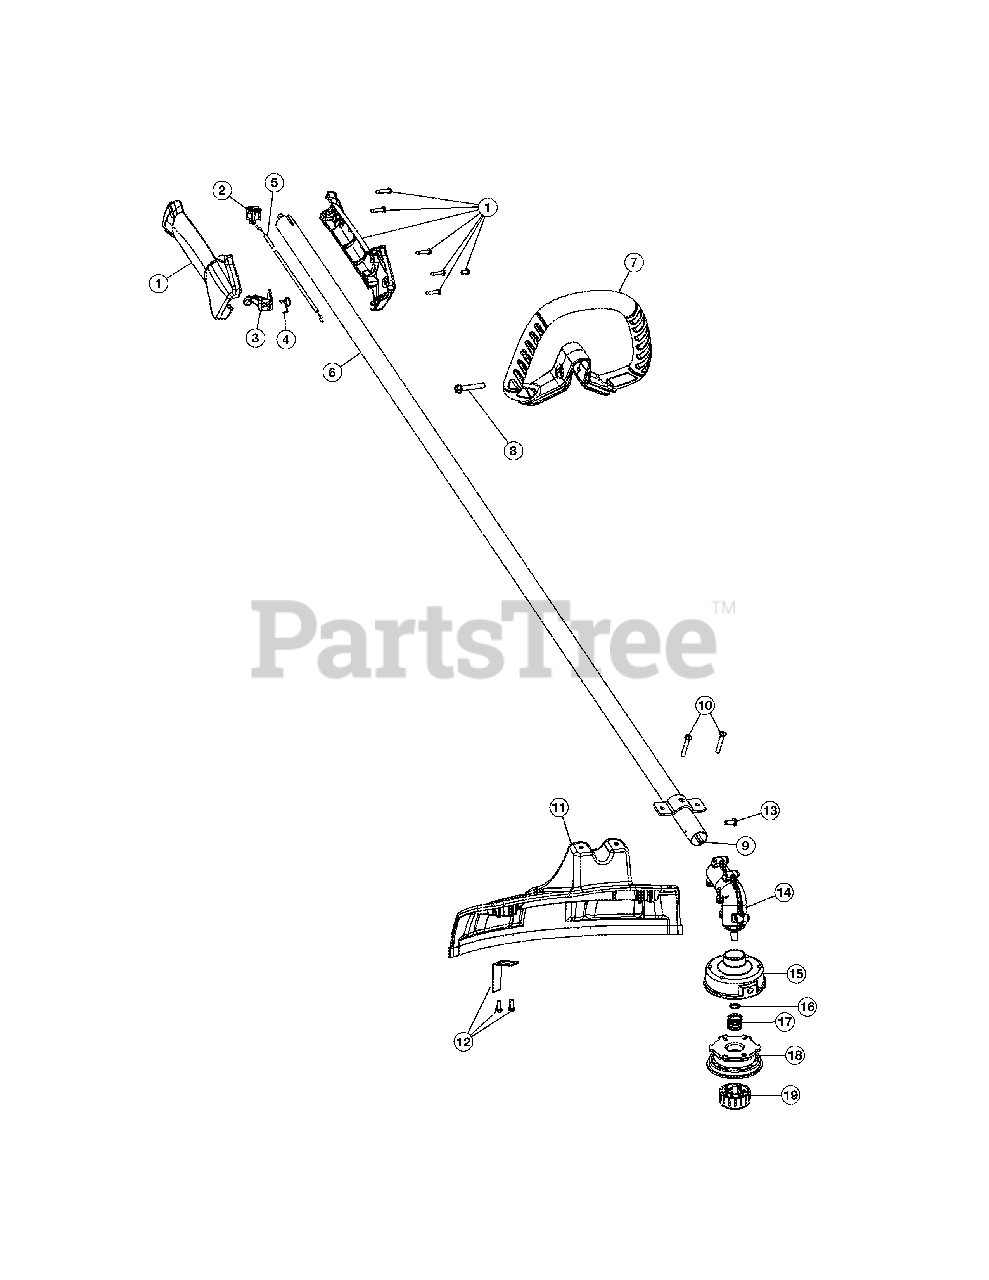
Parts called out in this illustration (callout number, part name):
1	Throttle Housing Assembly (includes 2-4)
3	Throttle Trigger
4	Throttle Trigger Spring
5	Throttle Cable
6	Drive Shaft Housing Assembly
7	Deluxe D-Handle Assembly (includes 8)
9	Flexible Drive Shaft
10	Guard Mounting Screw
11	Guard Assembly (includes 12)
12	Blade Assembly
13	Anti-Rotation Screw
14	Gearbox Assembly (includes 15-19)
15	Outer Spool Assembly (includes 16)
18	Inner Reel
19	Bump Head Knob Assembly
